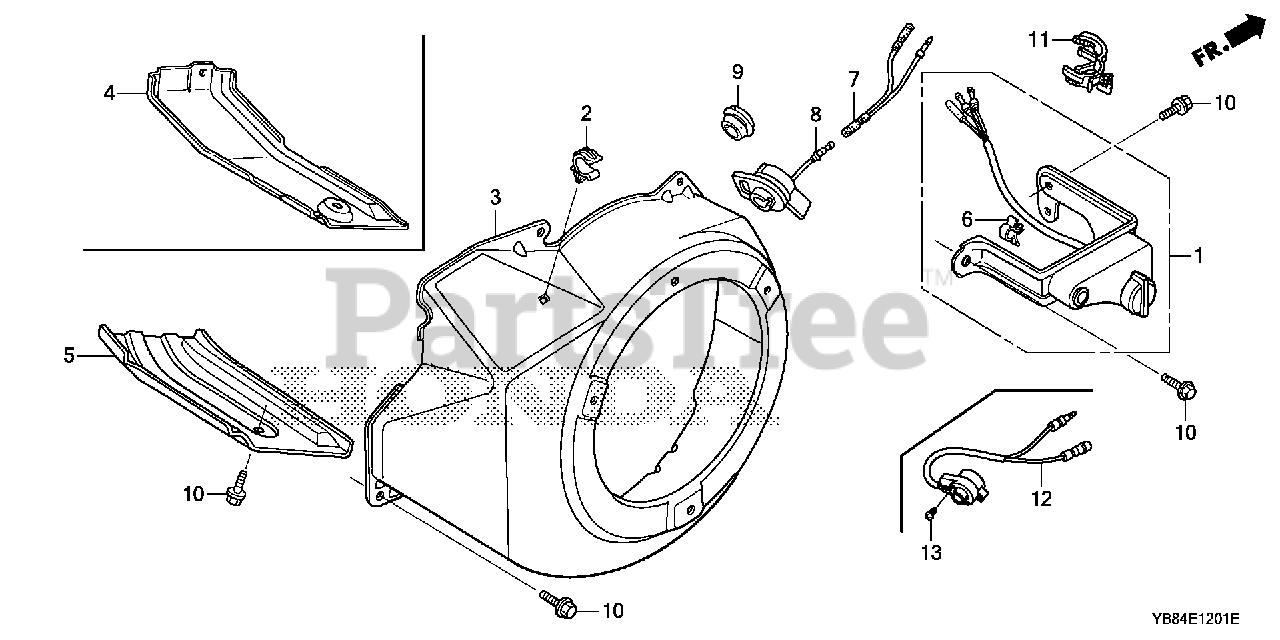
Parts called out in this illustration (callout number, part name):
2	CLIP, TUBE
3	COVER, FAN *R280* (POWER RED)
10	BOLT, FLANGE (6X12) (CT200)
11	CLIP, WIRE HARNESS
12	SWITCH ASSY., ENGINE STOP
13	SCREW, TAPPING (3X6) (PO)
